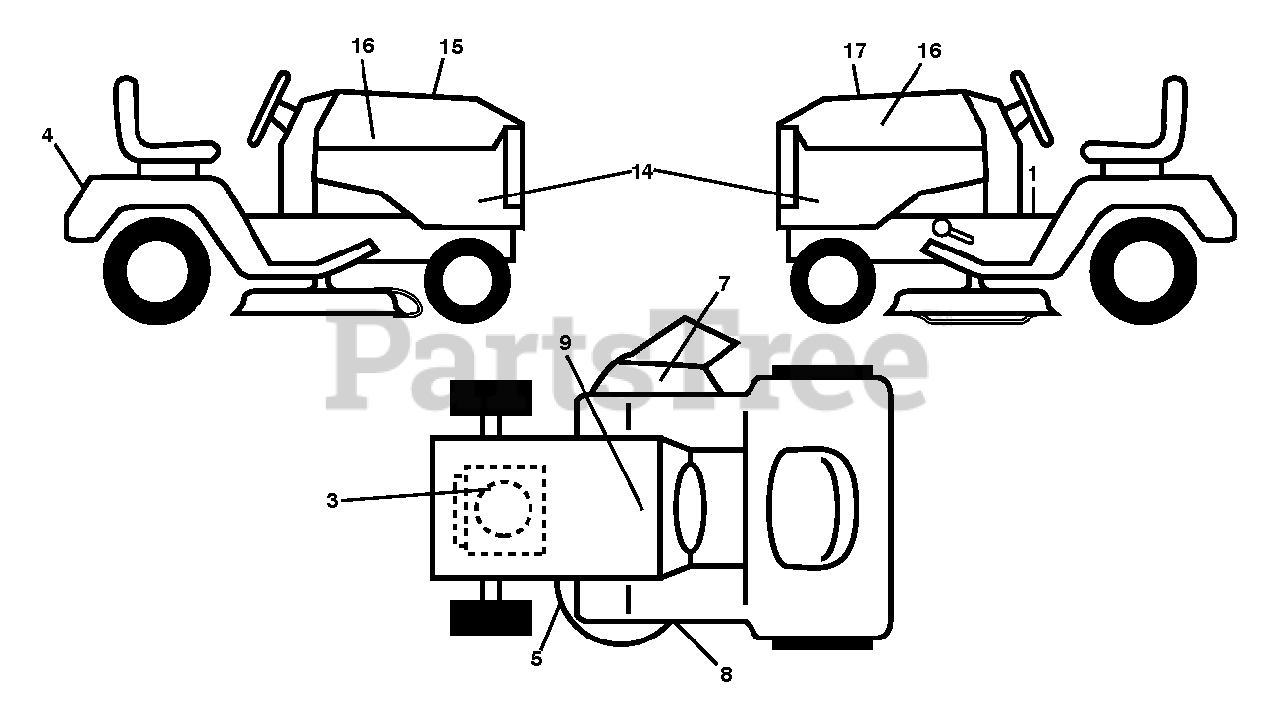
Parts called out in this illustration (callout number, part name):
1	DECAL TRACTOR LOWES DECAL DECA
3	DECAL.ENG.BS.INTK.24HP.382016
4	DECAL.FENDER
5	DECAL.MOWER.CAUTION.TENSION.AR
7	DECAL, DECK DEFLECTOR, WARNING
8	DECAL.MOWER.SCH.48/54.PREM
9	DECAL BTRY SYMBOLS
14	DECAL TRACTOR SIDE PANEL SDPNL
15	DECAL.WARNING.CUST.RESP.E85.
16	DECAL.BADGE.170MM.TEXTLOGO.
17	DECAL.RPL.BSM44.INTK.48.GENTR
